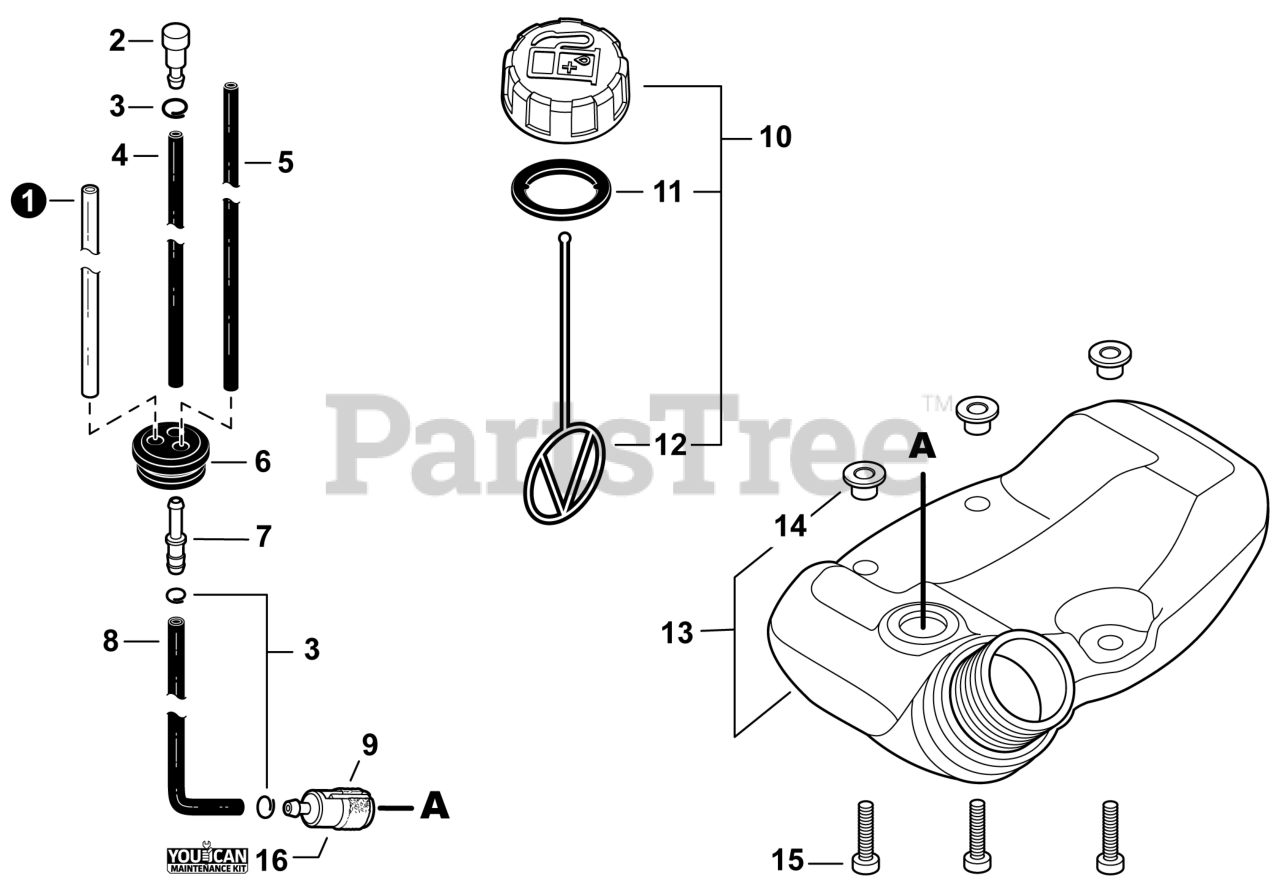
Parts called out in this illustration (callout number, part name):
1	PIPE, FUEL 3x6x80 YELLOW
2	VENT ASSY
4	PIPE, FUEL 3x5x90 BLACK
5	PIPE, FUEL 3x5.5x74 BLACK
6	GROMMET, FUEL 5
7	CONNECTOR, PIPE 5x3.5
8	PIPE, FUEL 3x5x90L BLACK
9	FILTER, FUEL
10	CAP ASSY, FUEL
11	GASKET, FUEL CAP
12	CONNECTOR, CAP L= 123
13	TANK ASSY, FUEL
14	COLLAR 5
15	BOLT, TORX 5x20
16	TUNE-UP KIT - YOUCANT
